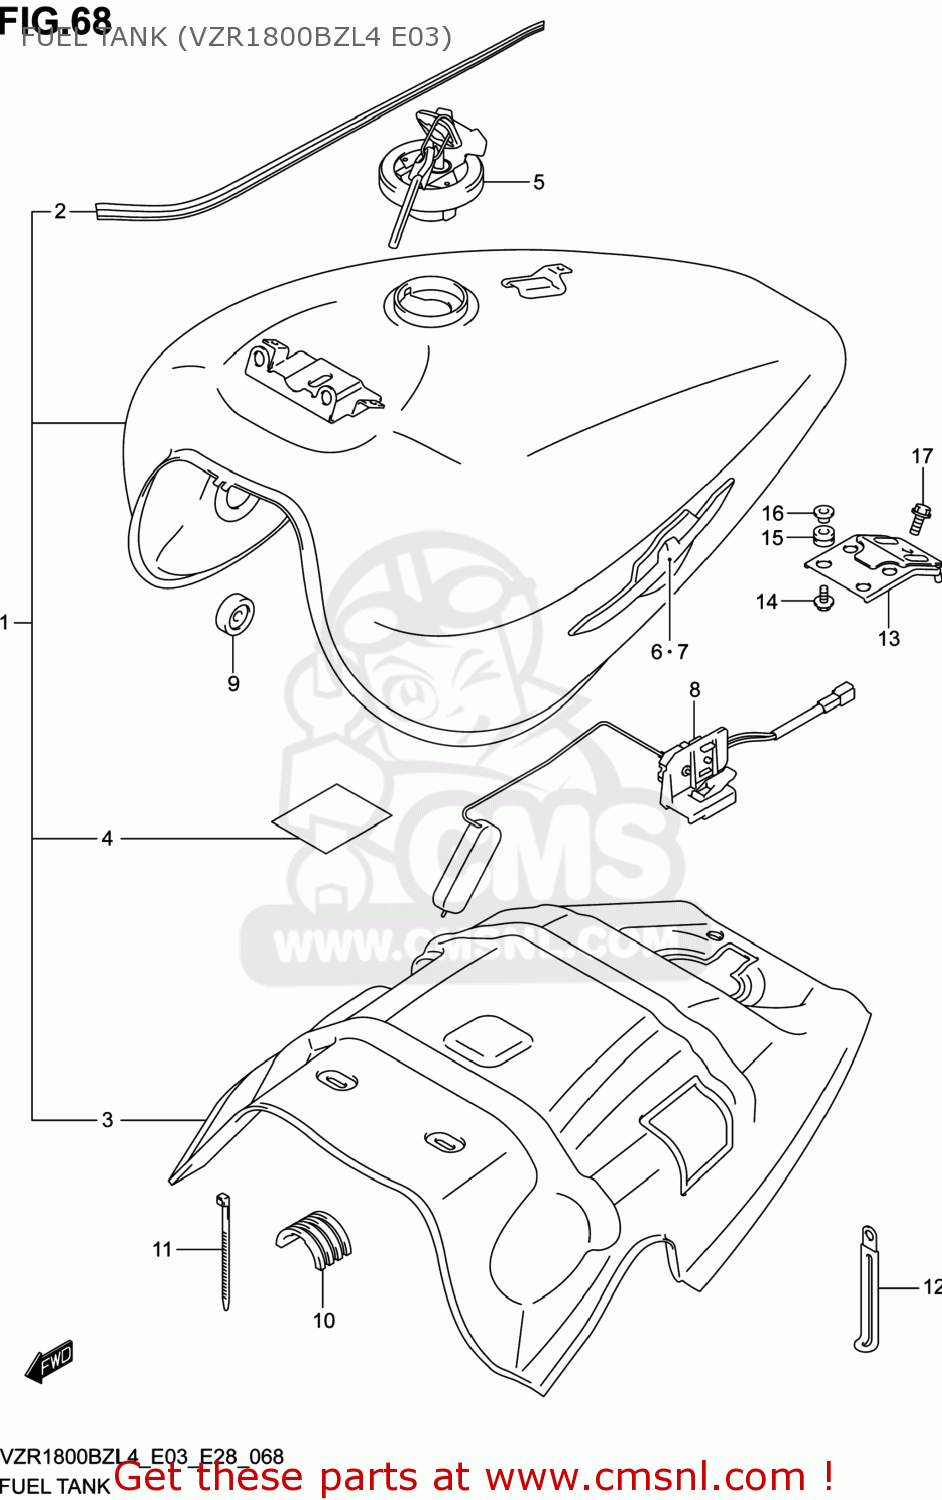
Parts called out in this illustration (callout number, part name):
1	TANK ASSY,FUEL
2	TAPE SET,FUEL TANK
3	SHIELD,FUEL TANK HEAT
4	TAPE,HEAT SHIELD
5	CAP SET,FUEL TANK
6	EMBLEM,FUEL TANK,R
7	EMBLEM,FUEL TANK,L
8	GAUGE ASSY,FUEL LEVEL SENDER
9	CUSHION
10	CUSHION,FUEL TANK
11	CLAMP(L:300)
12	CLAMP(L:80 T:1.0)
13	BRACKET,FUEL TANK RR
14	BOLT(6X20)
15	CUSHION
16	WASHER
17	BOLT
